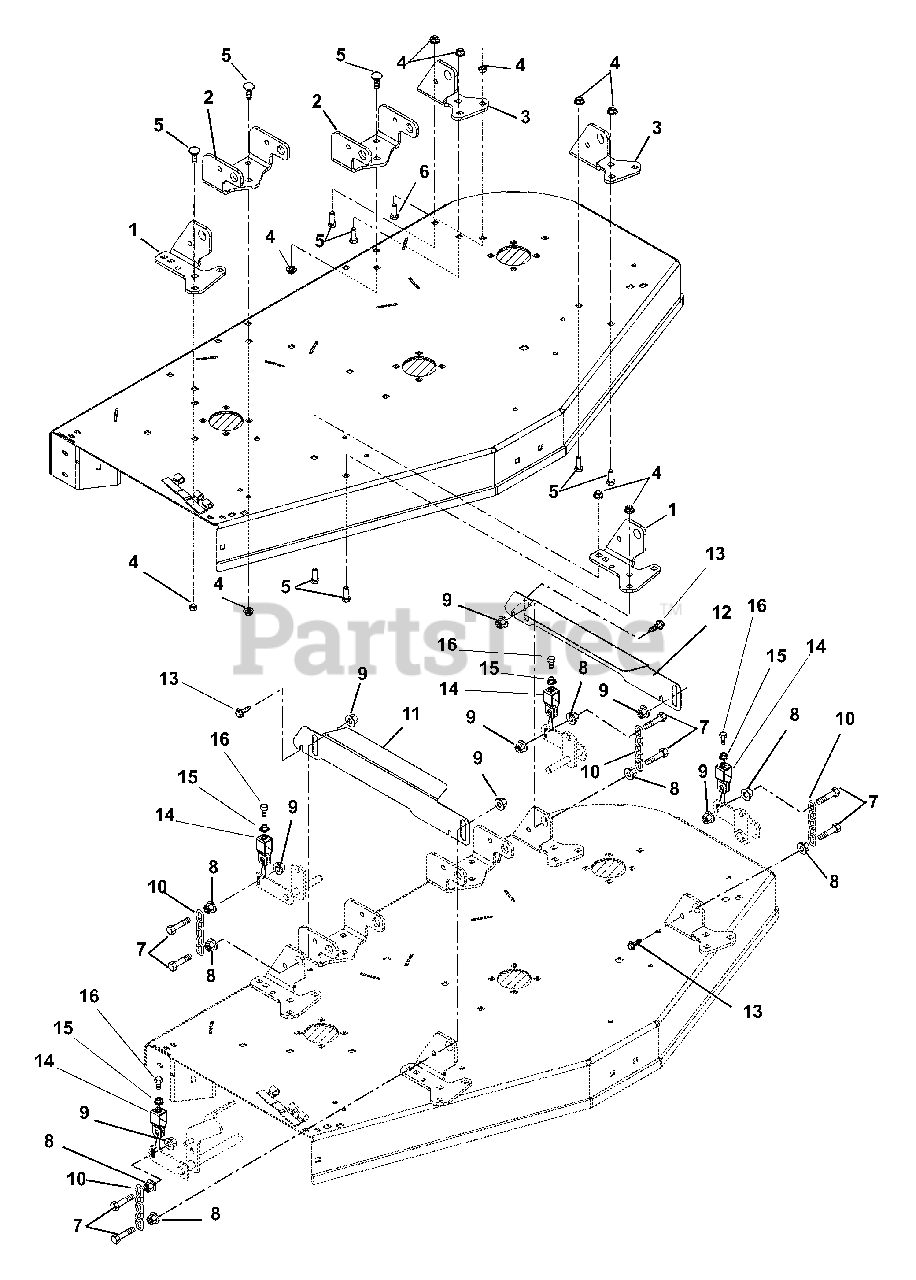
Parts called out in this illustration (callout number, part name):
1	Bracket, Deck Hanging
2	Bracket, Deck Mounting
3	Bracket, Deck Hanging
4	Nut, .38-16 Flange Nyloc
5	Bolt, Round Head Square Neck .38-16 x 1.00 Grade 5
6	Bolt, Round Head Square Neck .38-16 x 1.25 Grade 5
7	Bolt, Hex M12-1.75 x 50 Grade 8
8	Nut, Spinlock Flange M12-1.75
9	Nut, Locking Top Flange M12-1.75
10	Chain, Link
11	Bracket, Deck Stabilizing RH
12	Bracket, Deck Stabilizing LH
13	Screw, Tapping .25-20 x .50 Hex Washer Head
14	Bracket, Deck Leveling
15	Nut, Jam .312-18
16	Bolt, Hex .312-18 x 2.00 Full Thread Grade 5
